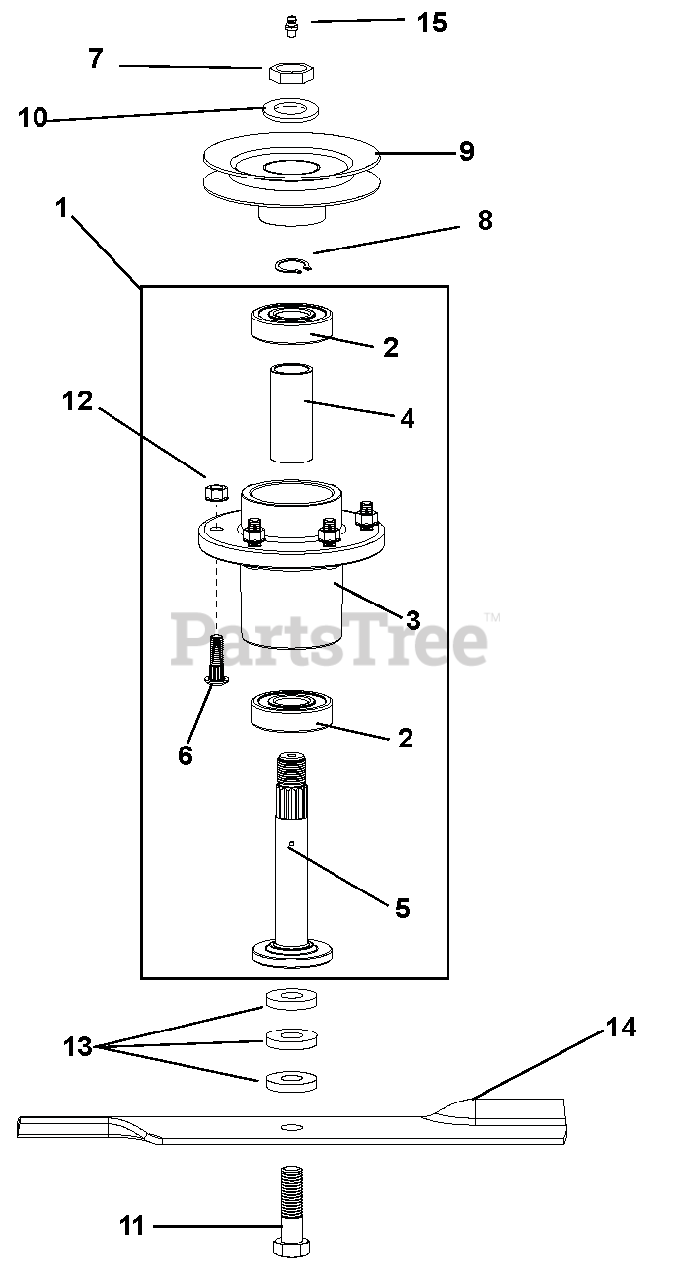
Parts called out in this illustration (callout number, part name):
1	ASSY, SPINDLE S/O
2	BALL BEARING
3	HOUSING
4	SPACER, 1.000 X 1.250 X 2.772
5	SHAFT, SPINDLE 3/4-16
6	BOLT, 3/8-16 X 1.25 RIB
7	LOCKNUT, 3/4-16 CROWN PL
8	RING RETAINER S/O
10	WASHER, .75X1.3125X.120
11	BOLT, 5/8-11 X 2.00 HEX 8 Y
12	@NUT-HEX .31-18 YWZC
13	SPACER, BLADE BOLT
14	18.0" BLADE, 52" DECK
15	FTG, 1/4-28 STRGT GREASE ZERK
